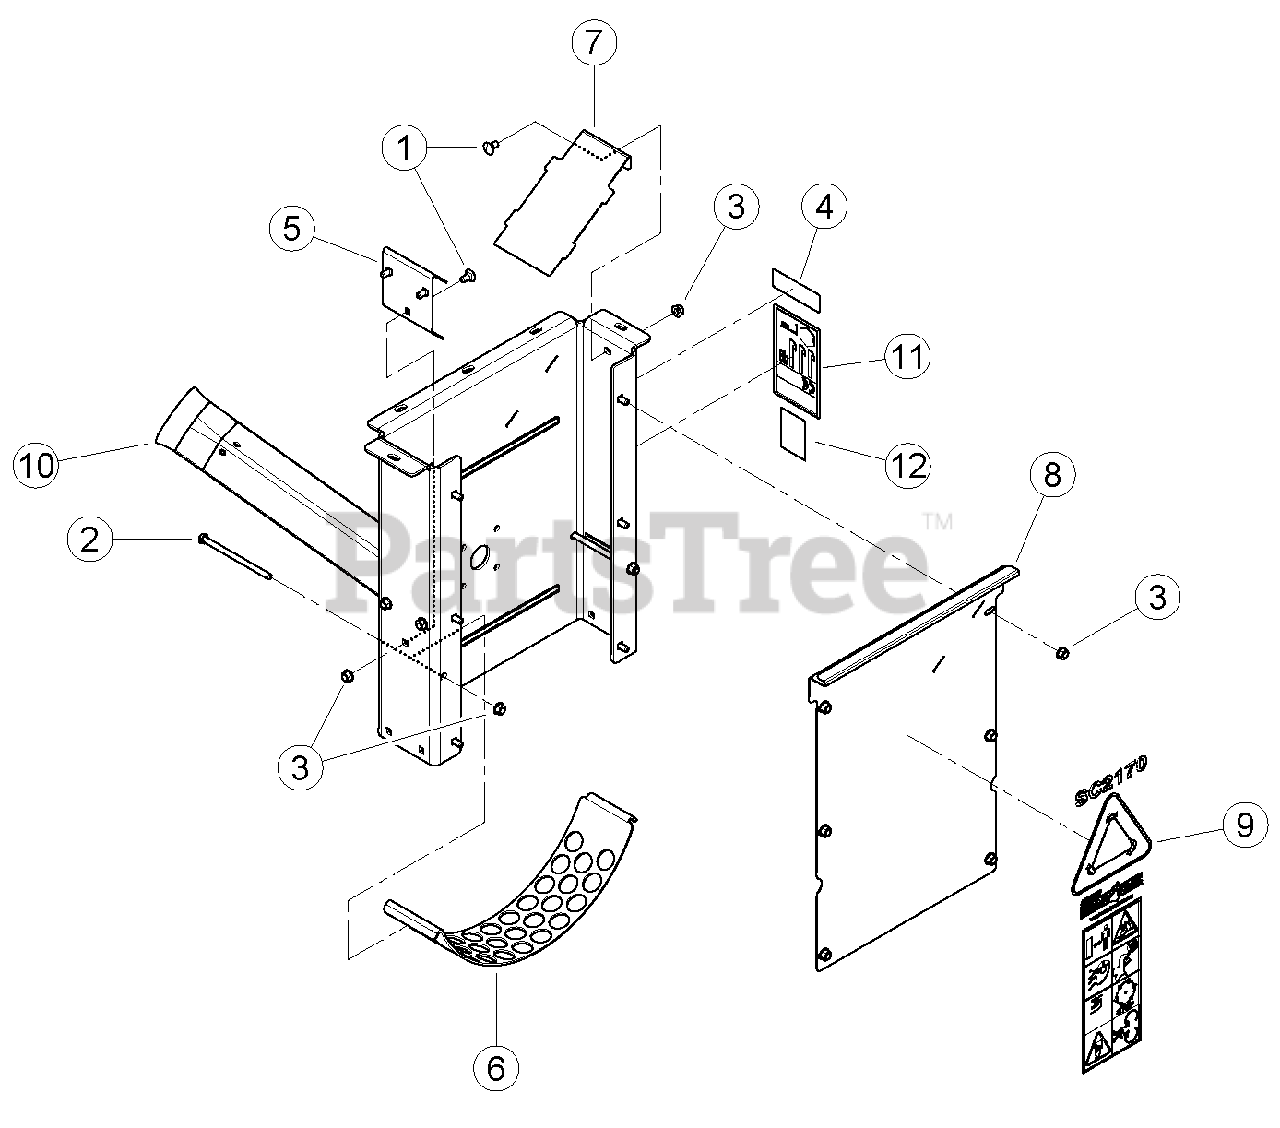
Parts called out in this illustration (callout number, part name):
1	BOLT, 5/16 X 5/8 CRG GR5 ZP
2	BOLT, 5/16 X 5 HEX HD NC GR5 ZP
3	NUT, 5/16 SPIRAL LOCK
4	DECAL, SERIAL NUMBER
5	PLATE, DEFLECTOR
6	SCREEN, SC2170 SMALL COARSE
7	PLATE, RESTRICTOR
8	ASSEMBLY, SC2170 PANEL SERVICE
9	DECAL, SC2170 INFORMATION
10	ASSEMBLY, SC2170 CHUTE SERVICE
11	DECAL, SC2170 CE INFORMATION
12	DECAL, ECHO BEARCAT QR CODE
